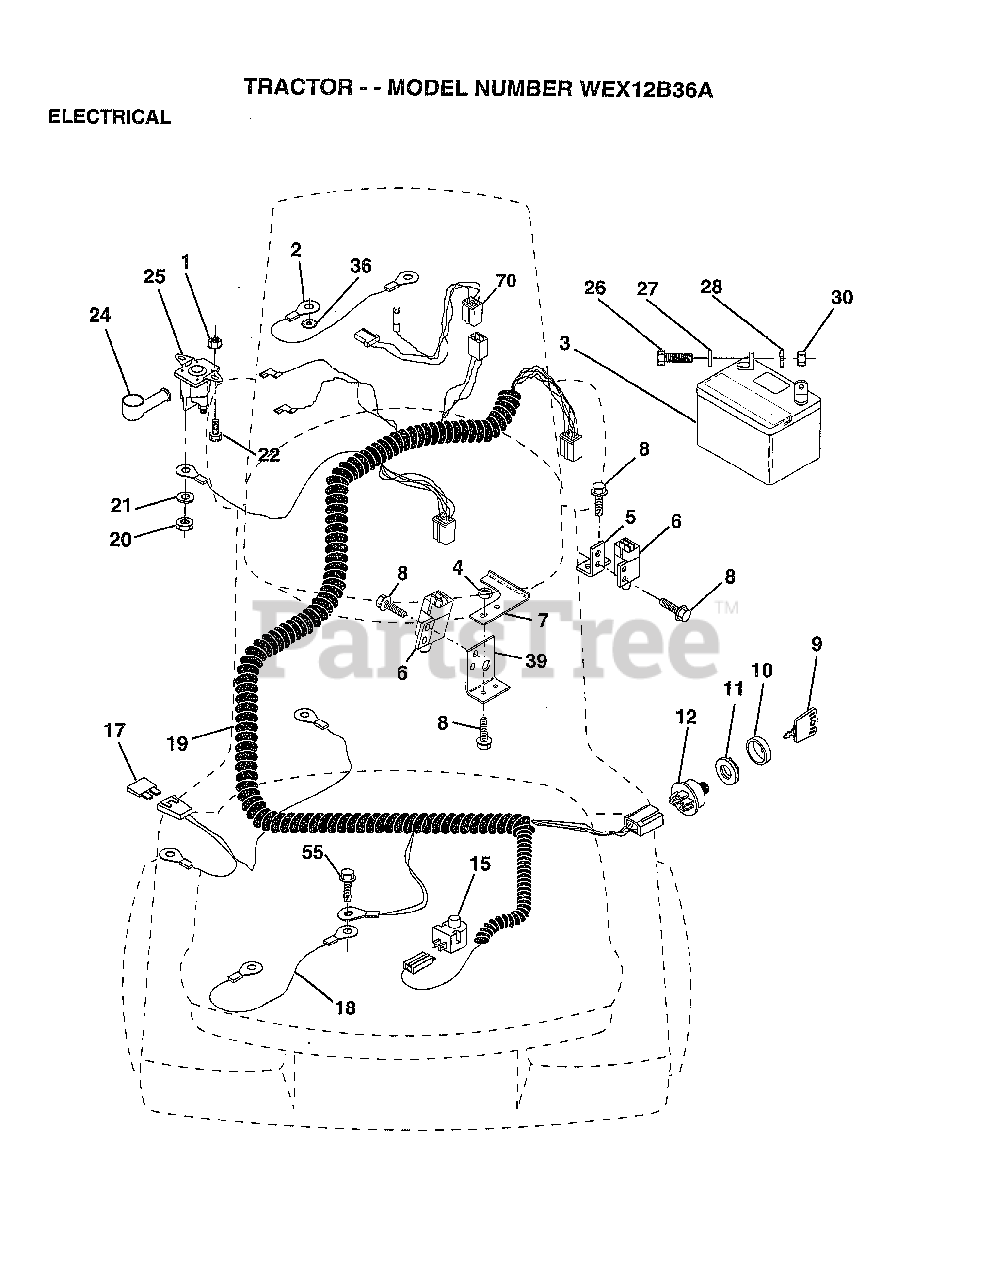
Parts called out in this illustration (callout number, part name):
1	NUT HXKEP 1/4X20
2	CABLE ASM.
4	LOCKNUT
5	BRACKET LT
6	SWITCH INTERLOCKT
7	KEEPER.ACTUAT.LR.
8	SCREW
9	KEY MLD GEN DELTA
10	COVER KEY SWITCH
15	SWITCH SEAT
17	FUSE HYT
18	CABLE ASSY
19	HARNESS.IGN.FEND.
20	NUT
22	BOLT HXHD FIN
26	BOLT LT
27	WASHER
28	LOCKWASHER
36	LOCKWASHER
39	BRACKET SWT CLUTC
55	SCREW LT
70	HARNESS ENG DUAL
